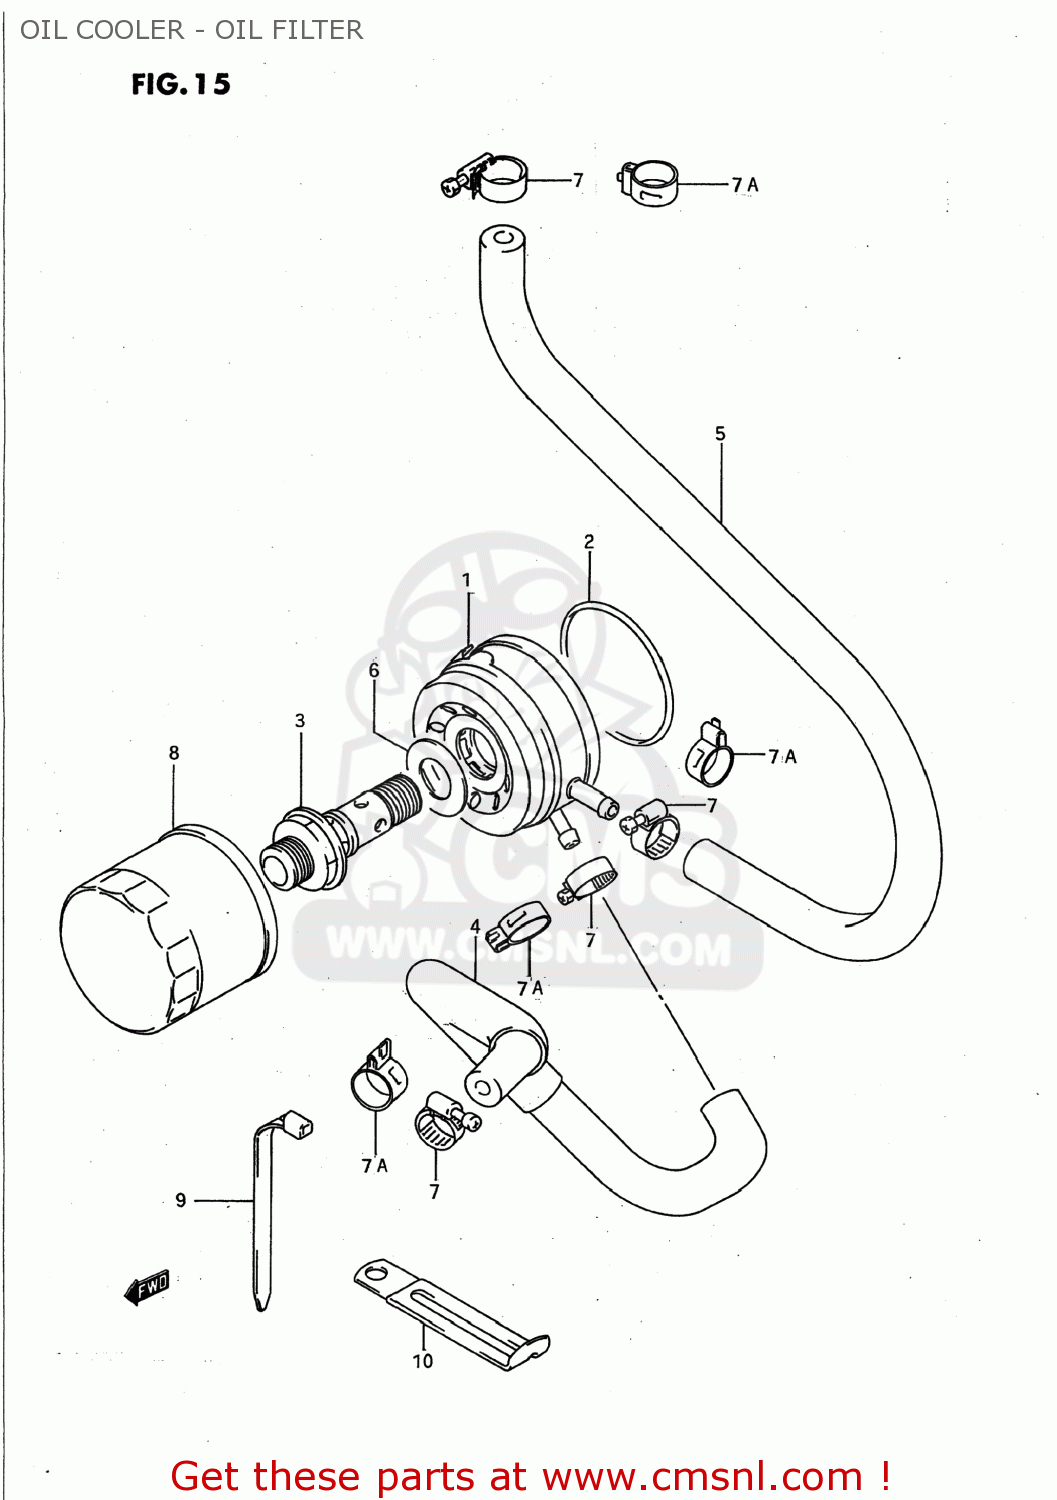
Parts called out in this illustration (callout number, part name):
1	COOLER ASSY,OIL
2	O RING(D:3.1,ID:63.9)
3	BOLT,OIL COOLER UNION
4	HOSE,OIL COOLER WATER IN
5	HOSE,OIL
6	SHIM
7	CLAMP
7A	CLIP
8	FILTER ASSEMBLY,ENGINE OIL
9	CLAMP(L:165)
10	CLAMP
